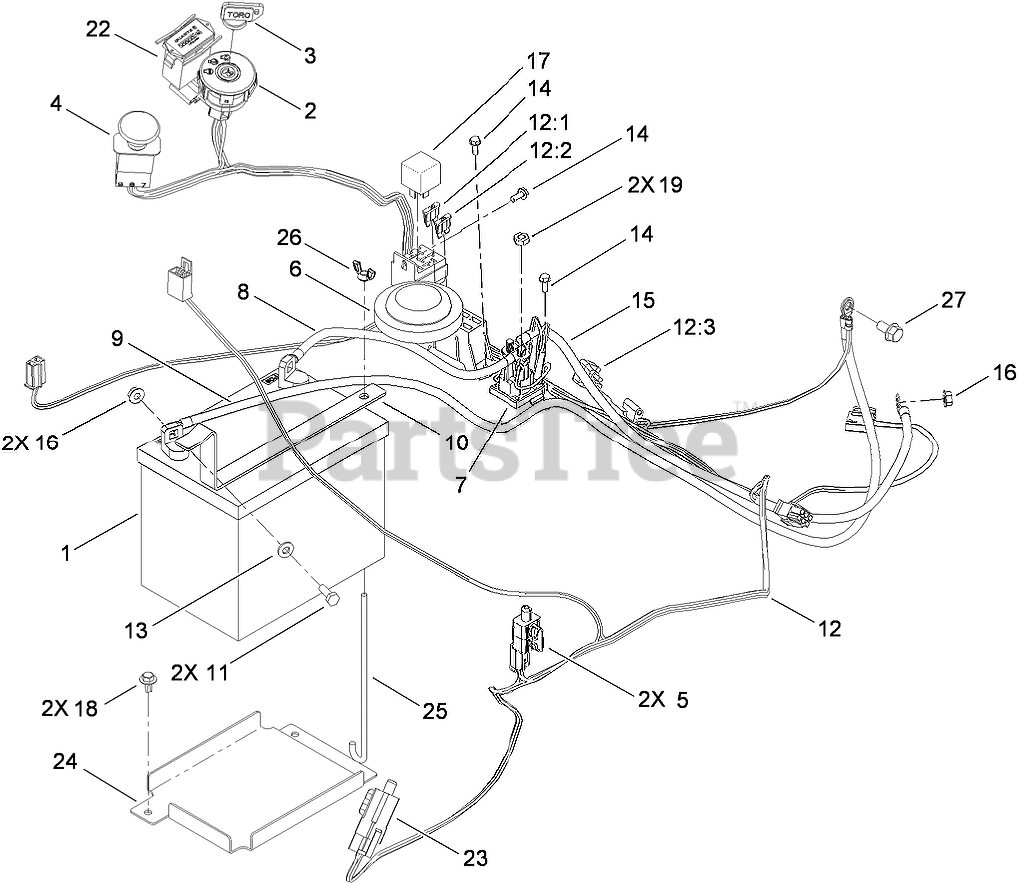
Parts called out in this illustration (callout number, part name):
1	BATTERY
2	SWITCH-IGNITION
3	KEY-IGNITION
4	SWITCH-PTO
5	SWITCH
6	SWITCH-SEAT
7	SOLENOID
8	CABLE-BATTERY, POSITIVE
9	CABLE-BATTERY, NEGATIVE
10	STRAP-BATTERY
11	SCREW-HH
12	Harness-Wire
12:1	FUSE-BLADE, 30 AMP
12:2	FUSE-BLADE, 25 AMP
13	WASHER-FLAT
14	SCREW-TAPTITE
15	WIRE-21 INCH
16	NUT-HF
17	RELAY
18	SCREW-HHFTF
19	NUT-JAM
22	METER-HOUR
23	SWITCH-REVERSE
24	TRAY-BATTERY
25	BOLT-HOLDDOWN
26	WINGNUT
27	SCREW-HHF
